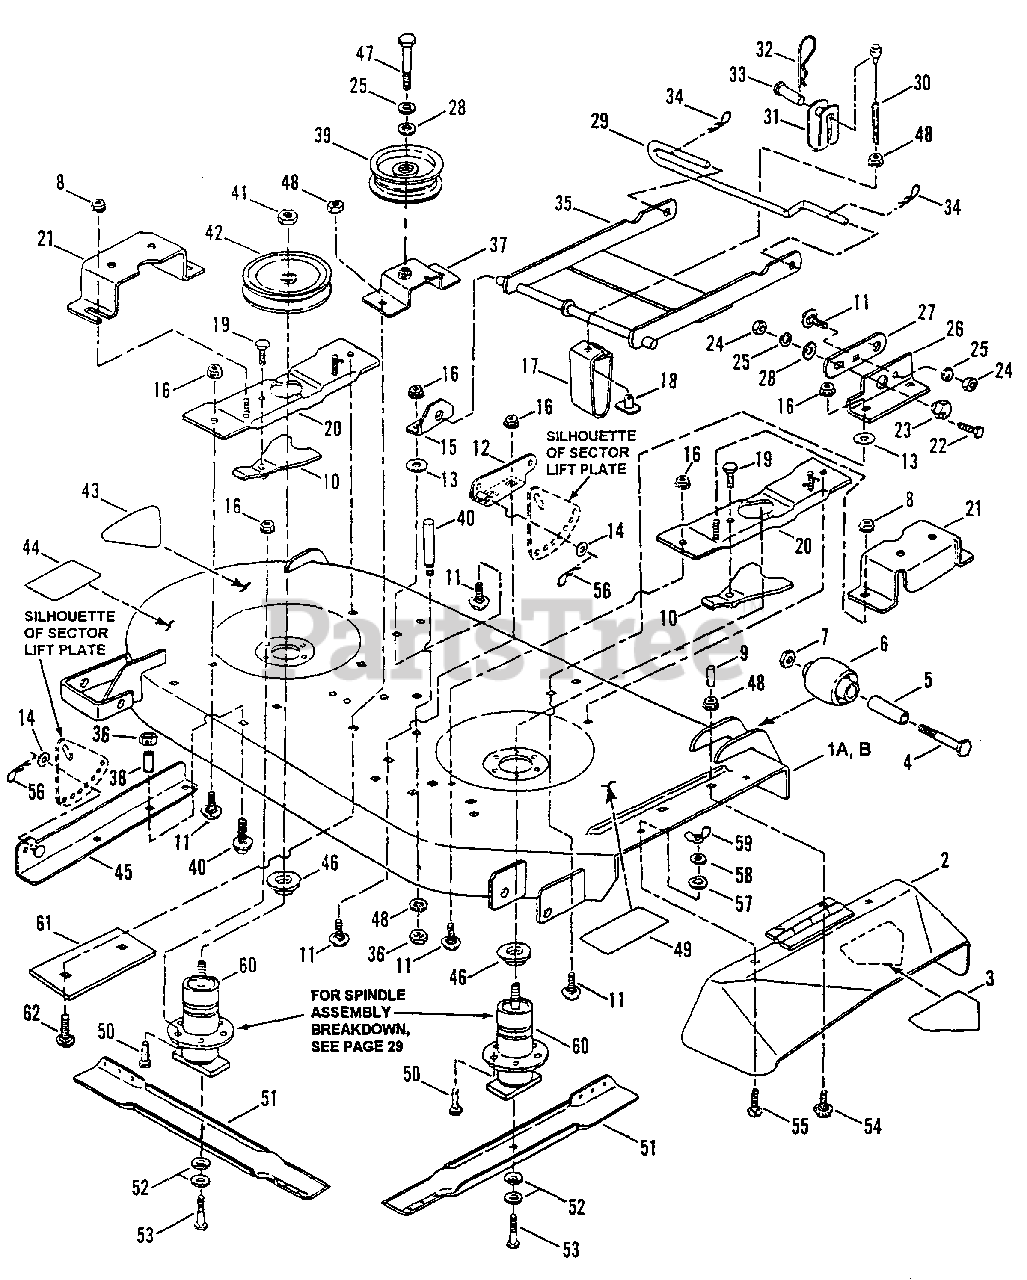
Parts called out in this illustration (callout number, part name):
1A	ASSEMBLY, Deck, 42" Cutting (Complete)
1B	ASSEMBLY, Deck, 42" Cutting (Includes Decals & Deflector)
2	DEFLECTOR, Side Discharge
3	DECAL-DANGER
4	SCREW, 3/8-24 x 3-3/4" Hex Head Cap Grade 5
5	SPACER
6	WHEEL, Gage
7	NUT, 3/8-24 Hex Center Lock, Grade 5 or B
8	NUT, 5/16-18 Hex Fl. Lk Gr.5
9	CAP, Vinyl
10	ASSEMBLY, Spindle Lock
11	BOLT, 3/8-16 x 3/4" Carr. Gr. 2
12	BRACKET, Lift (Right Side)
13	WASHER, Flat 3/8
14	WASHER, 3/8" Flat
15	BRACKET, Front Hanger (Left Side)
16	NUT, 3/8-16 Hex Flange Lock
17	BRACKET, Front Lift Arm Hanger
18	T-NUT, 5/16-18
19	BOLT, 3/8-16 x 1" Hx. Flange Lk.
20	ASSEMBLY, Spindle Brace
21	GUARD, Pulley
22	SCREW, 3/8-16 x 1" HHC, Gr.5
23	ECCENTRIC, Leveling
24	NUT, 3/8-16 Hex
25	WASHER, 3/8 Split Lock
26	BRACKET, Front (Right Side)
27	LINK, Adjustment
28	WASHER, 3/8" Flat
29	PIN, Deck Hanger
30	CABLE, Deck Lift
31	CLEVIS, Lift Cable
32	PIN, Hair, 3/32 x 1-1/2"
33	PIN, Clevis, 3/8 x 1-1/16"
34	PIN, Hair, .148 x 2.62"
35	ASSEMBLY, Front Hanger
36	NUT, 3/8 - 16 Hex Ctr Lk Gr. 5 or B
37	BRACKET, Idler
38	SLEEVE, 1/2 x 13/32 x 3/8
39	PULLEY, Idler 4-1/8"
40	BOLT, 3/8-16x1-1/2 Hx. Fl. Lk. Gr. 5
41	NUT, 3/4-16 Hex Jam
42	PULLEY, Spindle
43	DECAL, 42" Deck
44	DECAL - CAUTION (Rotating Blades)
45	BRACKET, Deck Lift (Left Side)
46	WASHER, Spindle
47	BOLT, 3/8-16 x 1-3/4 Hx. Fl. Lk.
48	NUT, 5/16-18 Hex Flange Lock Grade 5
49	DECAL - CAUTION (Deflector in Place)
50	BOLT, 3/8-16 x 3/4" Hex Flange Lock
51	BLADE, 21" Cutter
52	WASHER, Cone, 13/32 x 1-13/32 Diameter
53	SCREW, 3/8-24 x 1-1/4" Hex Head Cap, Grade 5
54	BOLT, 5/16-18 x 1" Short Neck Carriage, Grade 5
55	BOLT, 5/16-18 x 5/8" Carr. Gr. 5
56	PIN, Hair, 3/32 x 1-1/2"
57	RETAINER, 5/16 Bolt
58	WASHER, 5/16 Split Lock
59	WING-NUT, 5/16-18
60	ASSEMBLY, Spindle
61	PLATE, Support
62	SCREW, 5/16-18 x 1" Hex Head Cap, Grade 5
